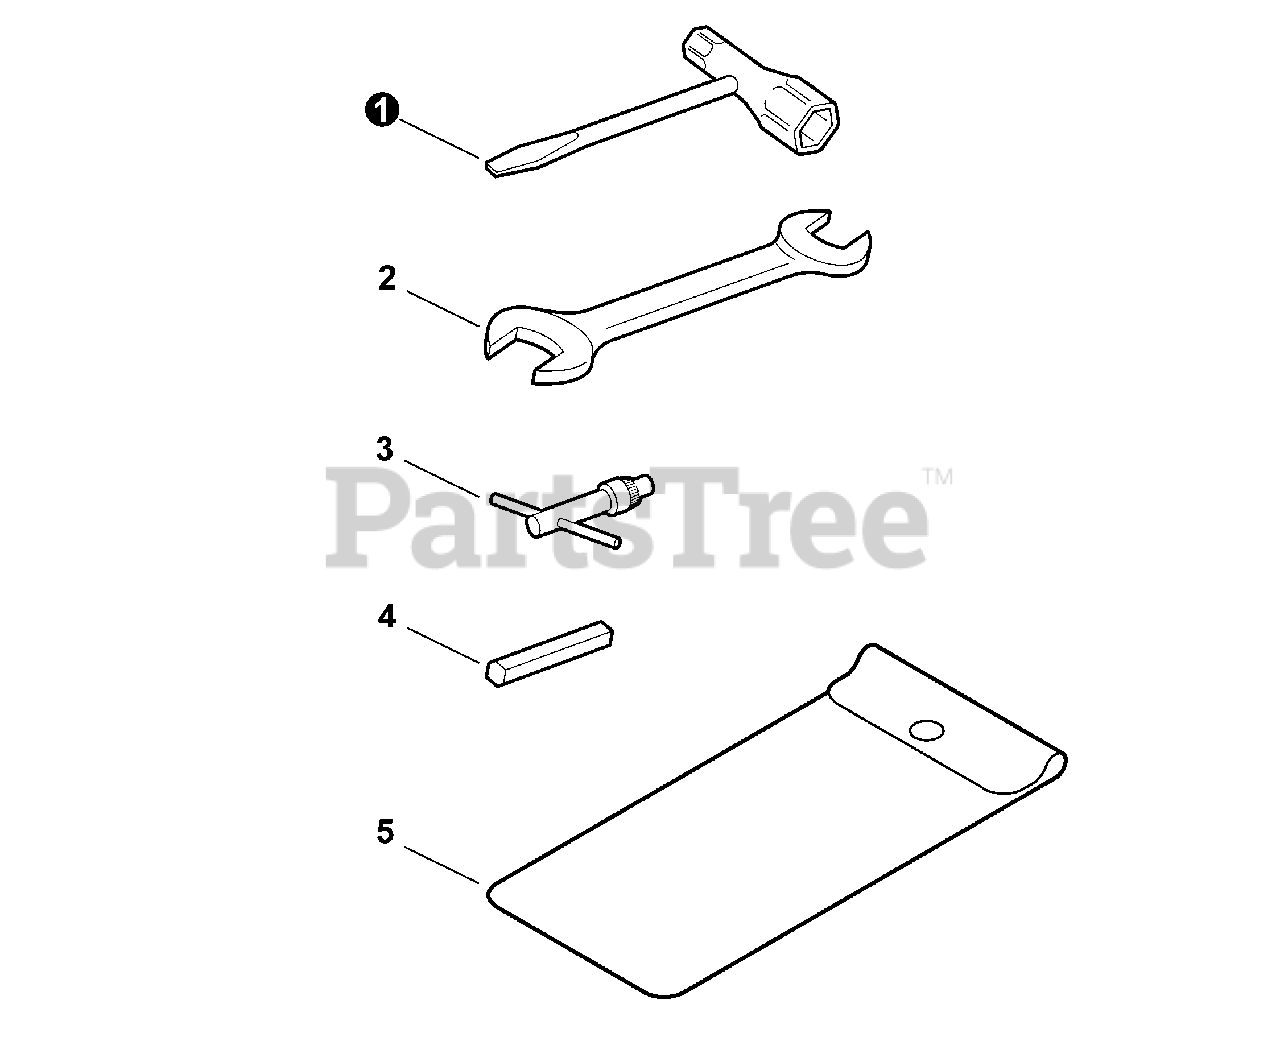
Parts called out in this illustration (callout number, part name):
1	T-WRENCH 10×19 MM
2	SPANNER 17×19
3	KEY, CHUCK
4	BAR, HEX
5	BAG, TOOL
